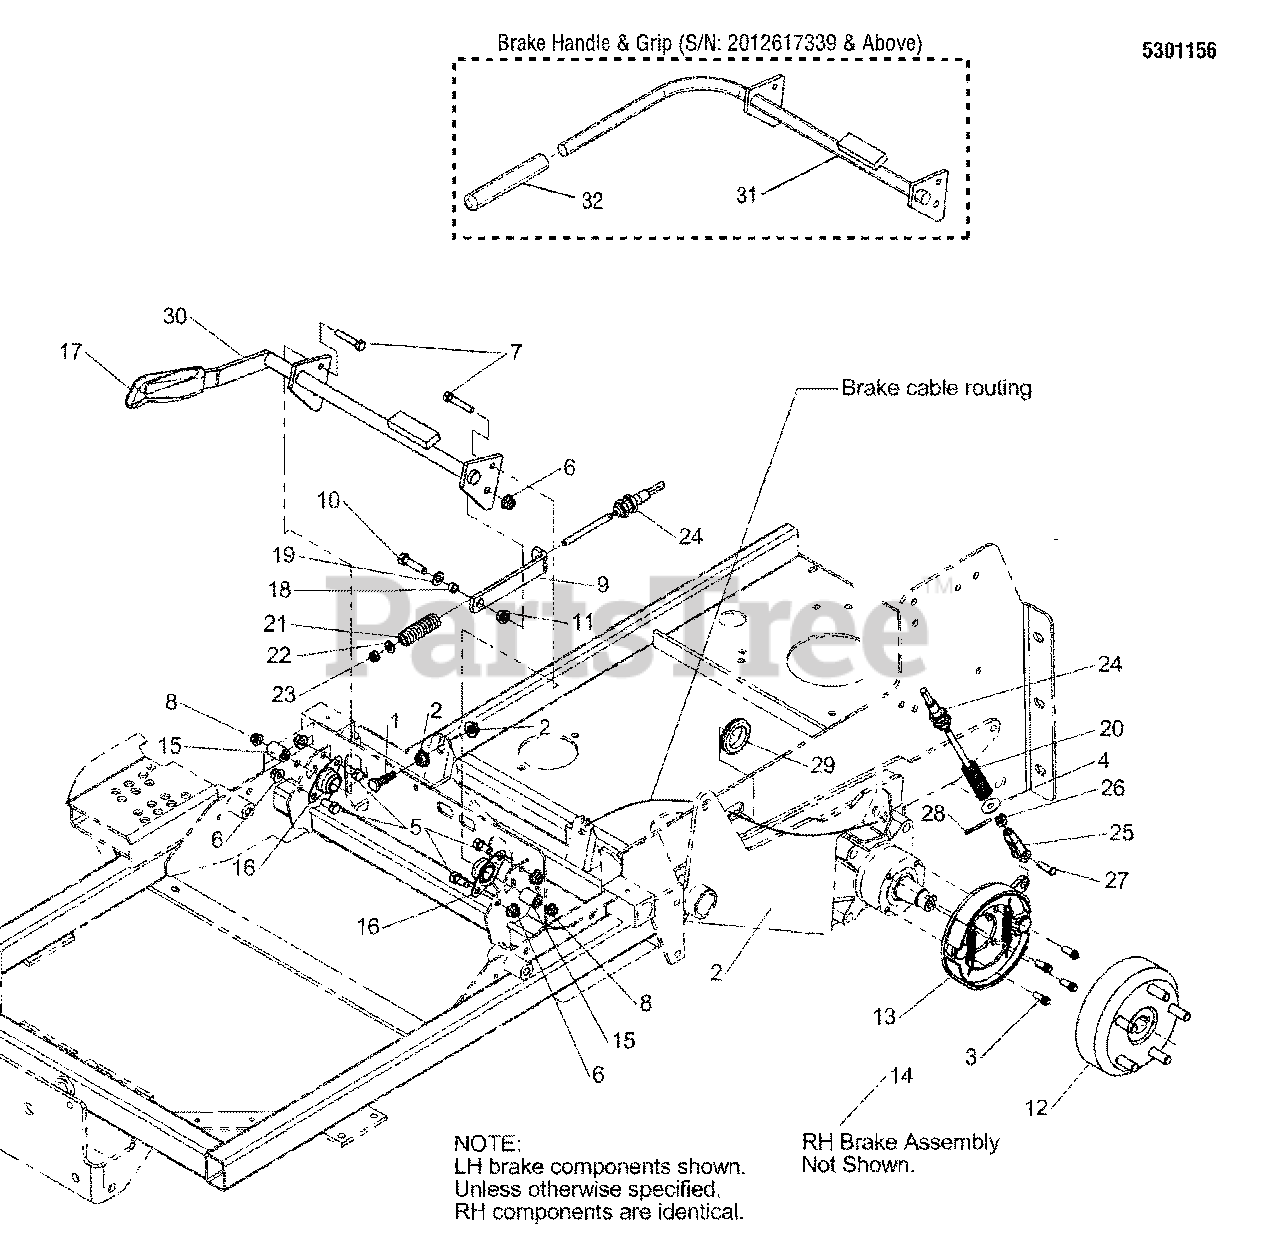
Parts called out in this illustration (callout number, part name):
1	BOLT, 5/16-18 X 1-1/8 GD5
2	NUT, 5/16-18 HEX SERRATED FLANGE (LARGE)
3	BOLT, 5/16-18 X 3/4 12PT FLANGE - PATCH
4	WASHER, 5/16 USS
5	BOLT, 3/8-16 X 3/4 GD5 YZ
6	NUT, 3/8-16 HEX NYLOCK FLANGE
7	BOLT, 5/16-18 X 1-3/4 GD5 YZ
8	NUT, 5/16-18 HEX NYLOCK FLANGE
9	LINK, BRAKE STOP, 6.0 - BLK
10	BOLT, 3/8-16 X 1-1/2 GD5 YZ
11	NUT, 3/8-16 HEX SERRATED FLANGE
12	DRUM,1-1/4TAPER,5 BOLT
13	BRAKE ASSEMBLY, LH
15	SPACER, .32 X .75 X 1.06
16	BEARING, BRONZE FLANGE, 3/4
17	GRIP, BLACK FLEXIBLE
18	SPACER, .38 X .50 X .27
19	WASHER, 3/8 SAE
20	SPRING, COMPRESSION
21	SPRING-COMP, .428ID X 2.50LG X .155WR
22	WASHER, 5/16 SAE
23	NUT, 5/16-24 HEX NYLON LOCK
24	CABLE, PARKING BRAKE
25	CLEVIS, 5/16-24, PLASTIC
26	NUT, 5/16-24 HEX
27	PIN, CLEVIS, 5/16 X 1 YZ
28	PIN, HAIR, .0585 X 1-1/8, 1/4 EYE, YZ
29	GROMMET, 1-1/4
30	WELD, BRAKE SHAFT
31	WELD, BRAKE SHAFT - BLK
32	GRIP, FOAM 3/4 ID X 6 X .187
